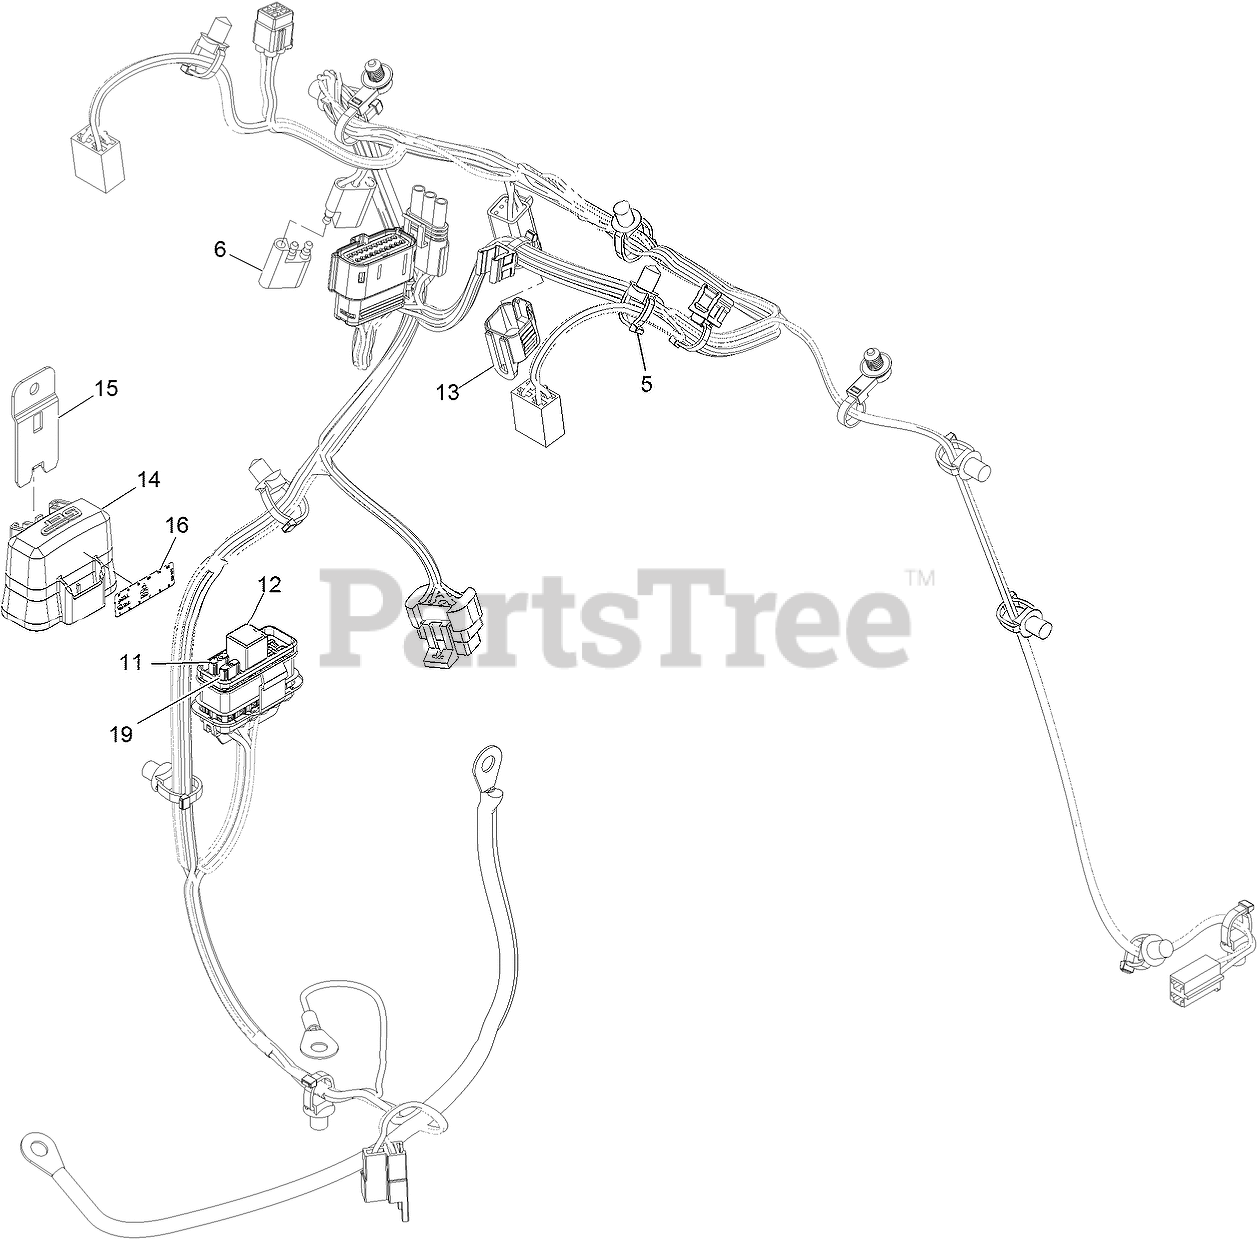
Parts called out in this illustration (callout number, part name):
5	CLIP-TIE
6	Cap-Plug
11	FUSE-MINI BLADE, 20 AMP
12	RELAY-MICRO
13	CAP-PLUG, 6 WAY
14	COVER-BLOCK, FUSE
15	CLIP-MOUNTING
16	Decal-Fuse
19	FUSE-MINI BLADE, 15 AMP
